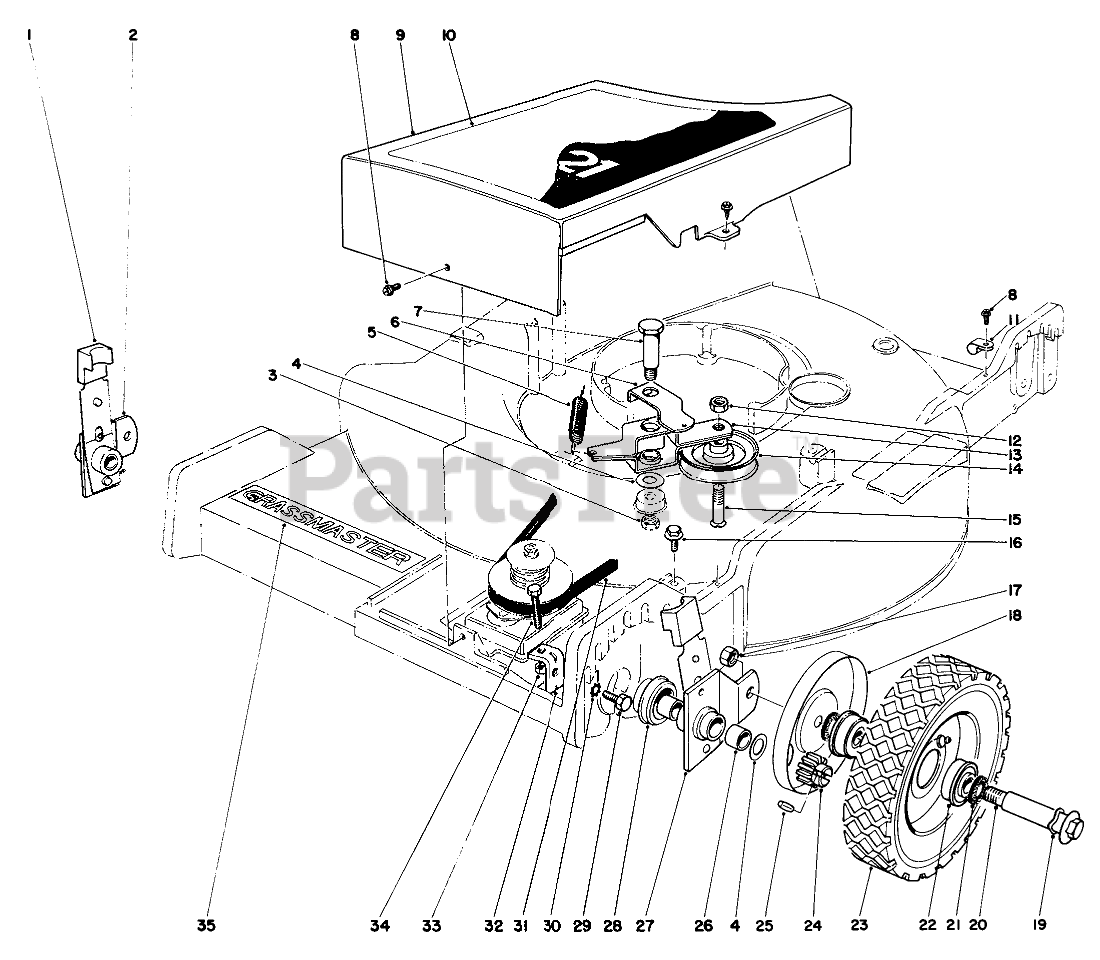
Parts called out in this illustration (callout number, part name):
1	Knob
2	Pivot Arm R.H. (Incl. Ref. #26)
3	NUT-HEX
4	WASHER-THRUST
5	TENSION SPRING
6	Idler Bracket Lever
7	SCREW-SHOULDER, HH
8	SCREW
9	Belt Cover
10	Decal Belt Cover
11	CLAMP-NYLON
12	NUT-HEX
13	Idler Bracket
14	V-GROOVE IDLER PULLEY
15	Screw Low Head
16	SCREW-HWHTF
17	Nut
18	WHEEL COVER
19	SPRING WASHER
20	WHEEL BOLT
21	FELT WASHER
22	BEARING-BALL
23	Wheel & Tire Assembly (Incl. Ref. #22)
24	Pinion
25	PIN-GROOVED
26	BUSHING
27	Pivot Arm L.H. (Incl. Ref. #26)
28	End Cap
29	SCREW-HH
30	WASHER-LOCK
31	V-BELT
32	Bracket
33	NUT-LOCK
34	Screw
35	Decal Grassmaster
